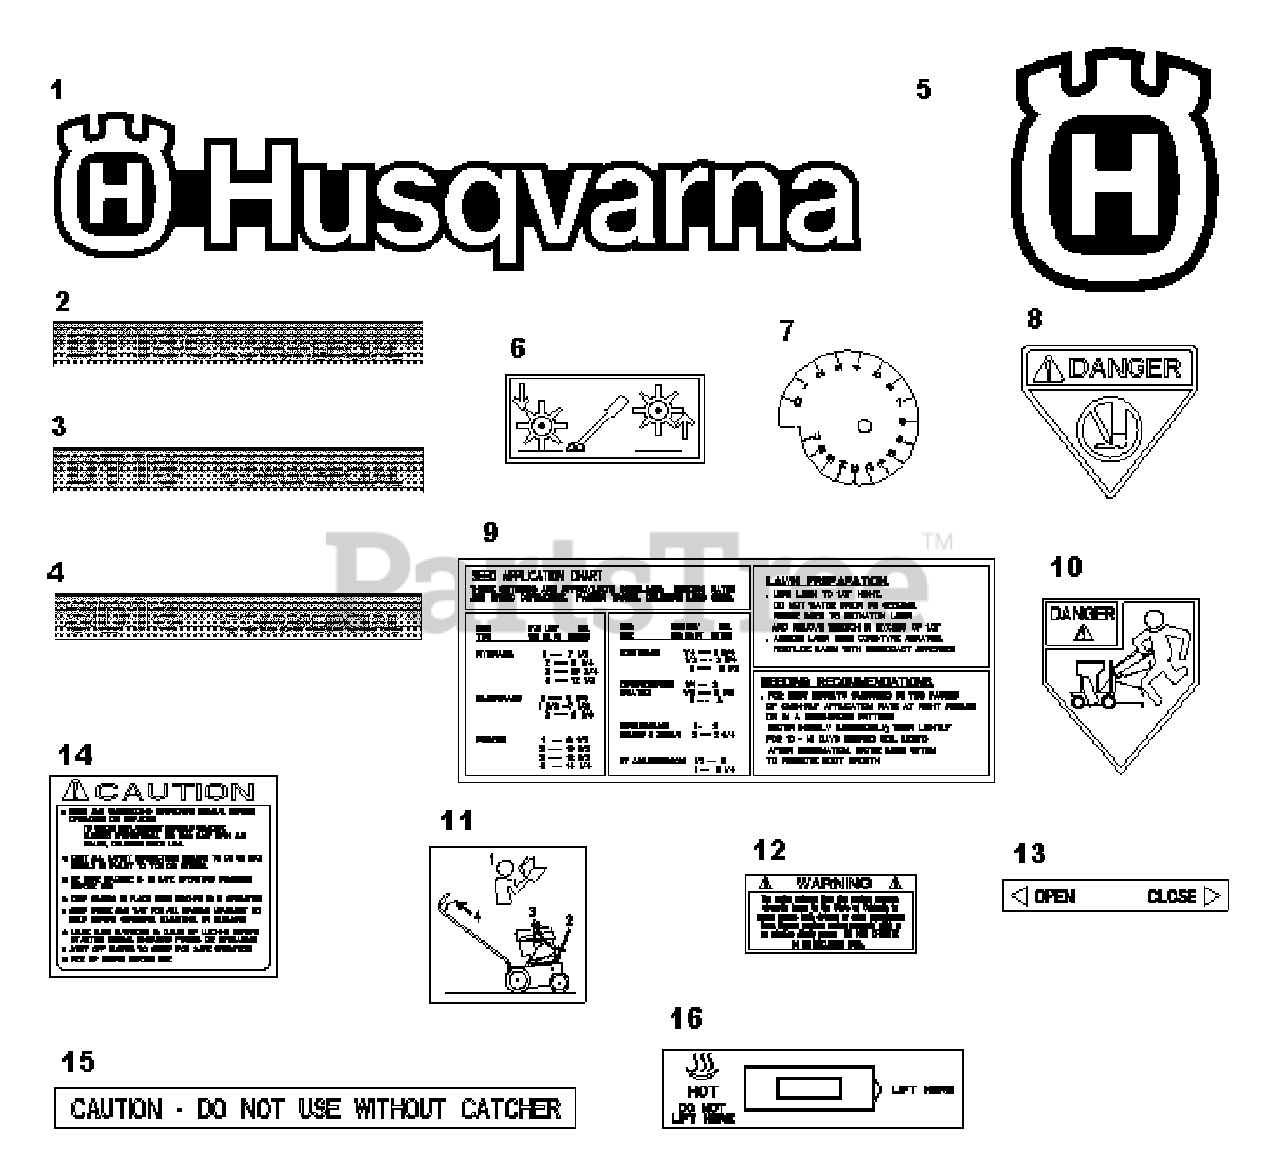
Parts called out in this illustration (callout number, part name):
1	Decal, Husqvarna Logo
2	Decal, DT18C Dethacher
3	Decal, DT18 Dethacher
4	Decal, SD18 Seeder
5	Decal, Husqvarna Crown
6	Decal, Height Adjusment
7	Decal, Gage Dial
8	Decal, Danger Foot
9	Decal, Seed Application
10	Decal, Danger Chute
12	Decal, Warning Carbon Monoxide
13	Decal, Open / Close,
14	Decal, Caution List
15	Decal, Caution Catcher
16	Decal, HOT Seeder Lid
